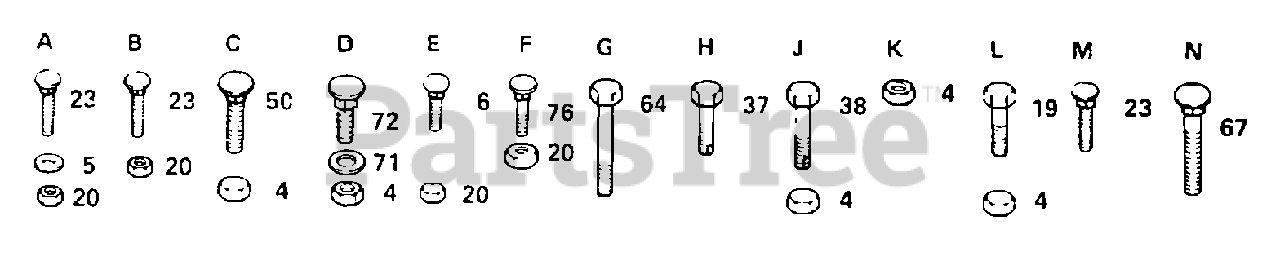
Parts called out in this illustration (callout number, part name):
5	WASHER M
6	BOLT
23	BOLT
37	SCREW
38	SCREW
50	BOLT
67	BOLT.3/8-14X1.25
71	WASHER
72	BOLT
